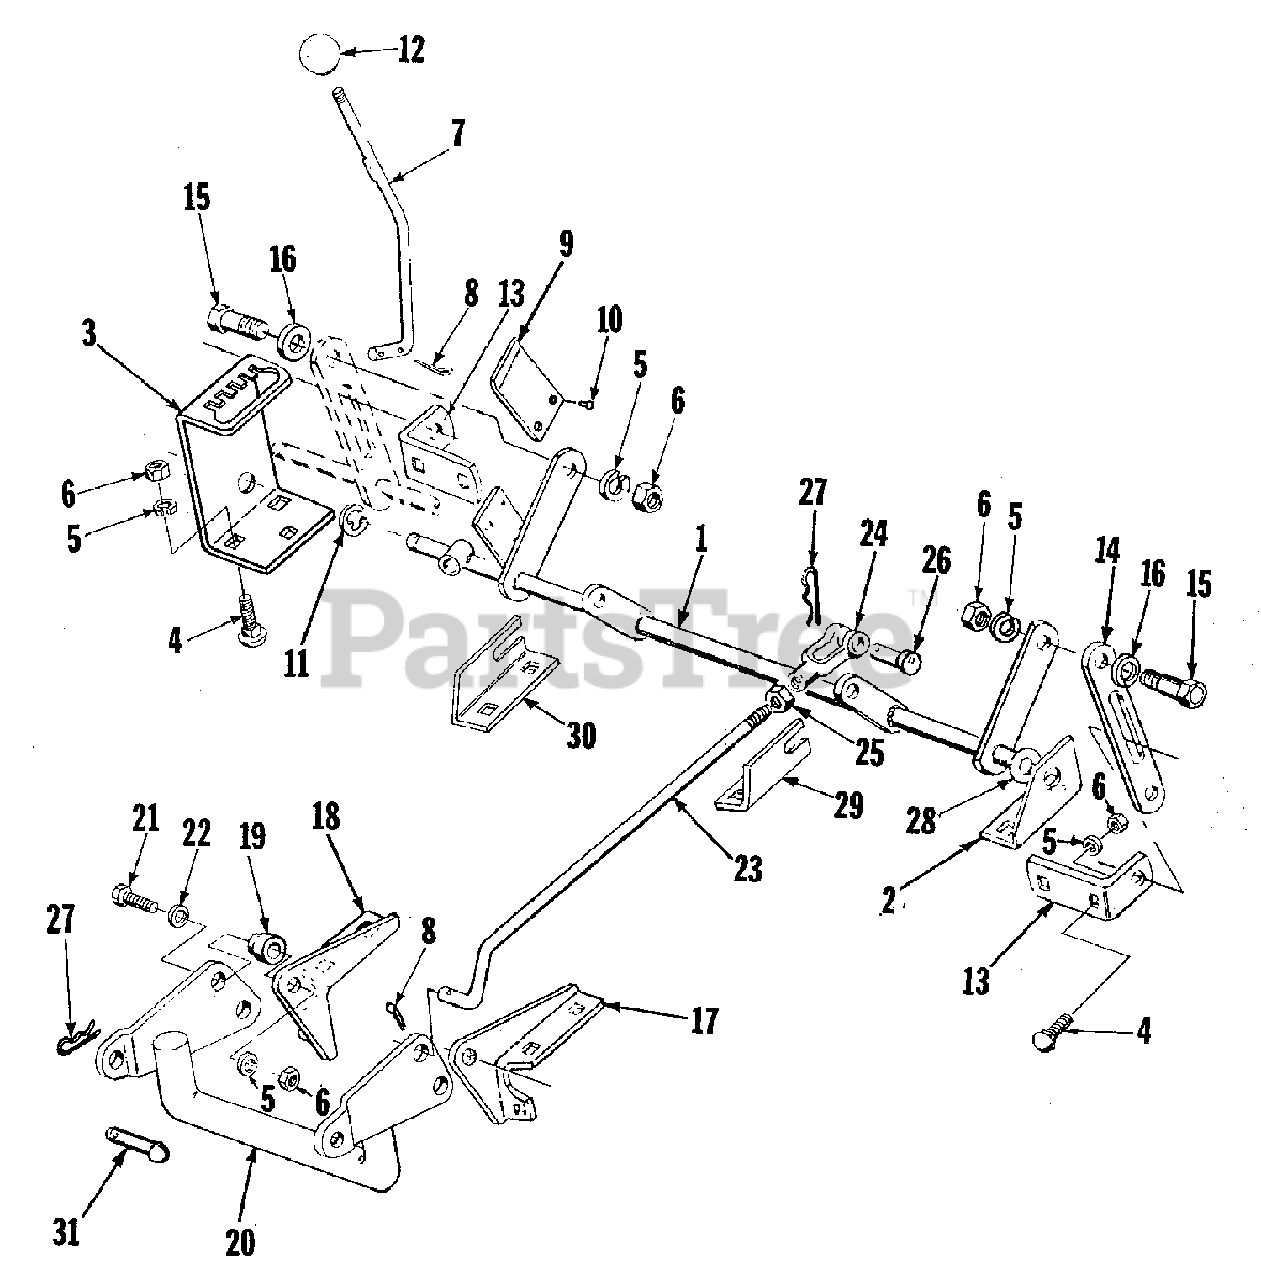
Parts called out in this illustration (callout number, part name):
1	ARM ASSEMBLY, Mower
2	BRACKET, Pivot (L.H.)
3	QUADRANT, Mower Control
4	BOLT, Round Head, 3/8-16 x 3/4
5	WASHER, Lock, 3/8"
6	NUT, Hex, 3/8-16
7	LEVER, Control
8	PIN, Cotter, 1/8 x 1
9	SPRING, Mower Quadrant
13	BRACKET, Roller Support
15	BOLT, Shoulder
16	WASHER, Flat, 7/16
17	BRACKET, Front (L.H.)
18	BRACKET, Front (R.H.)
19	SPACER, Pivot
20	LINK ASSEMBLY, Mower
21	SCREW, Hex Head Cap, 3/8-16 x 1-3/4
22	WASHER, Flat
23	ROD, Adjusting (R.H.) 42" Mower
23	ROD, Adjusting (R.H.) 48" Mower
23	ROD, Adjusting (L.H.) 42" Mower
23	ROD, Adjusting (L.H.) 48" Mower
24	YOKE, Rod End Adjusting
25	NUT, Jam Hex, 1/2-20
26	PIN, Yoke, 1/2
28	WASHER, Flat, 25/32 x 1-1/8
29	SUPPORT, Shaft (L.H.)
30	SUPPORT, Shaft (R.H.)
31	PIN, Round Head
